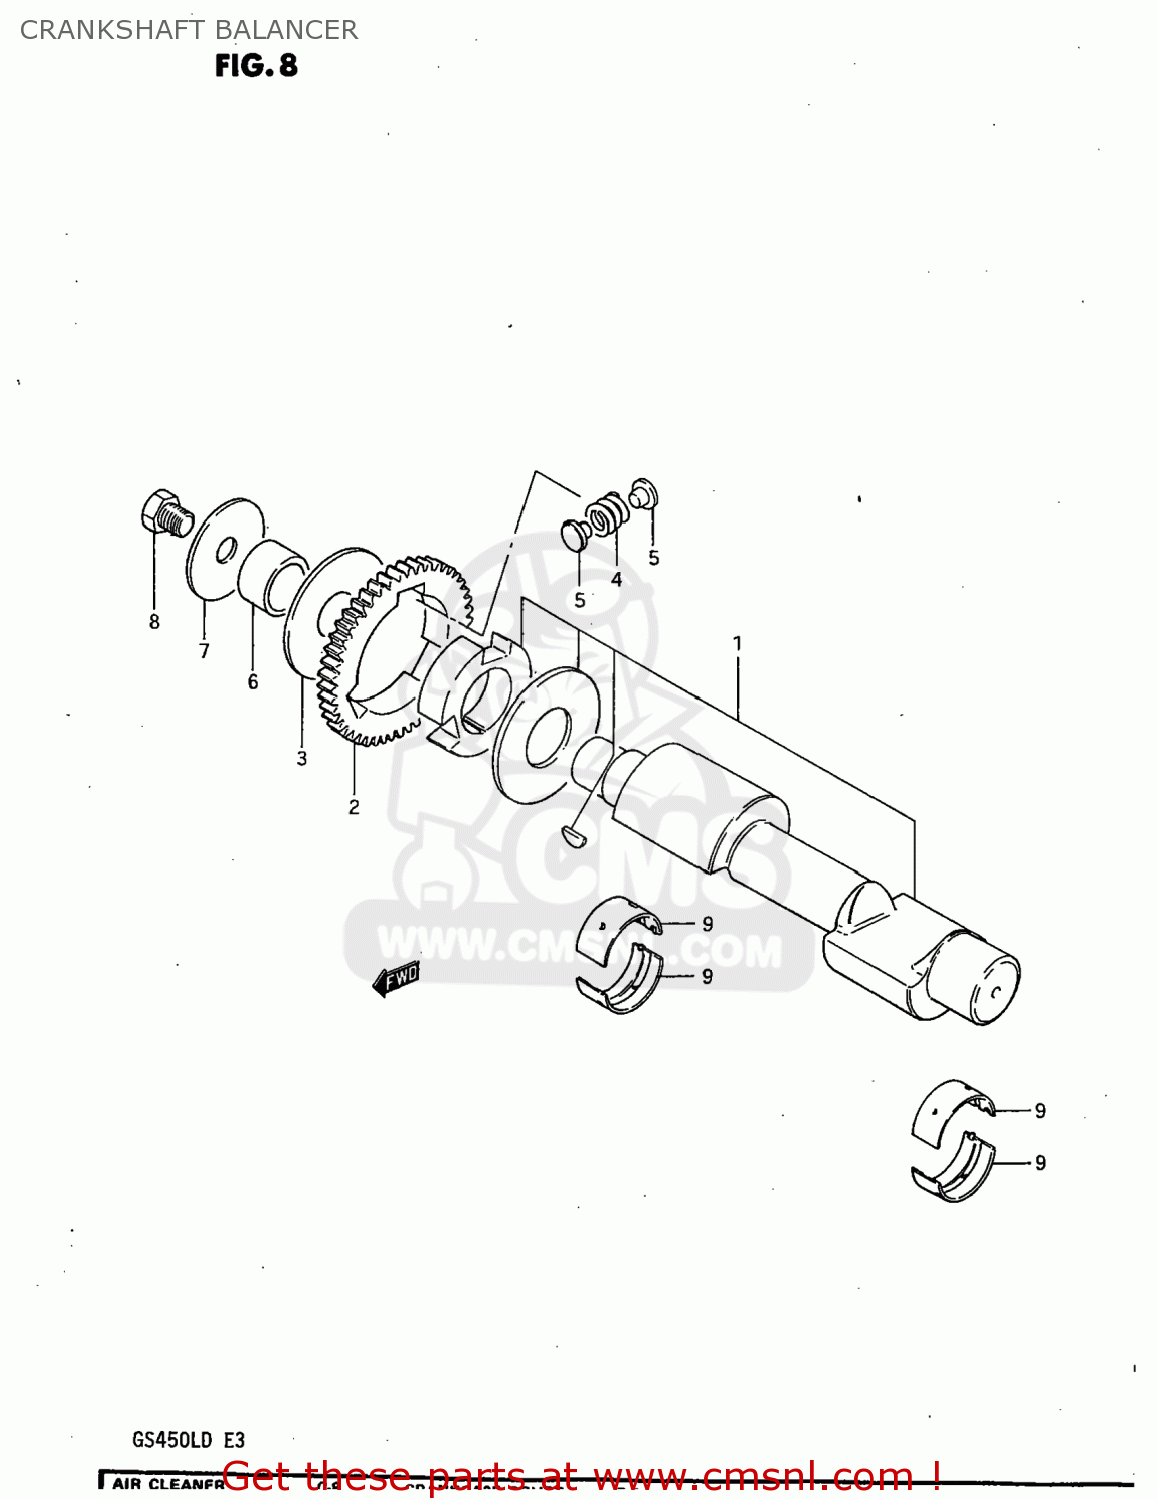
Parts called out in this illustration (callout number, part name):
1	BALANCER,CRANKSHAFT
2	GEAR,CRANK BALANCER DRIVE
3	WASHER
4	SPRING
5	PIN
6	SPACER
7	WASHER(12X50X3)
8	BOLT
9	METAL CRANKSHAFT
